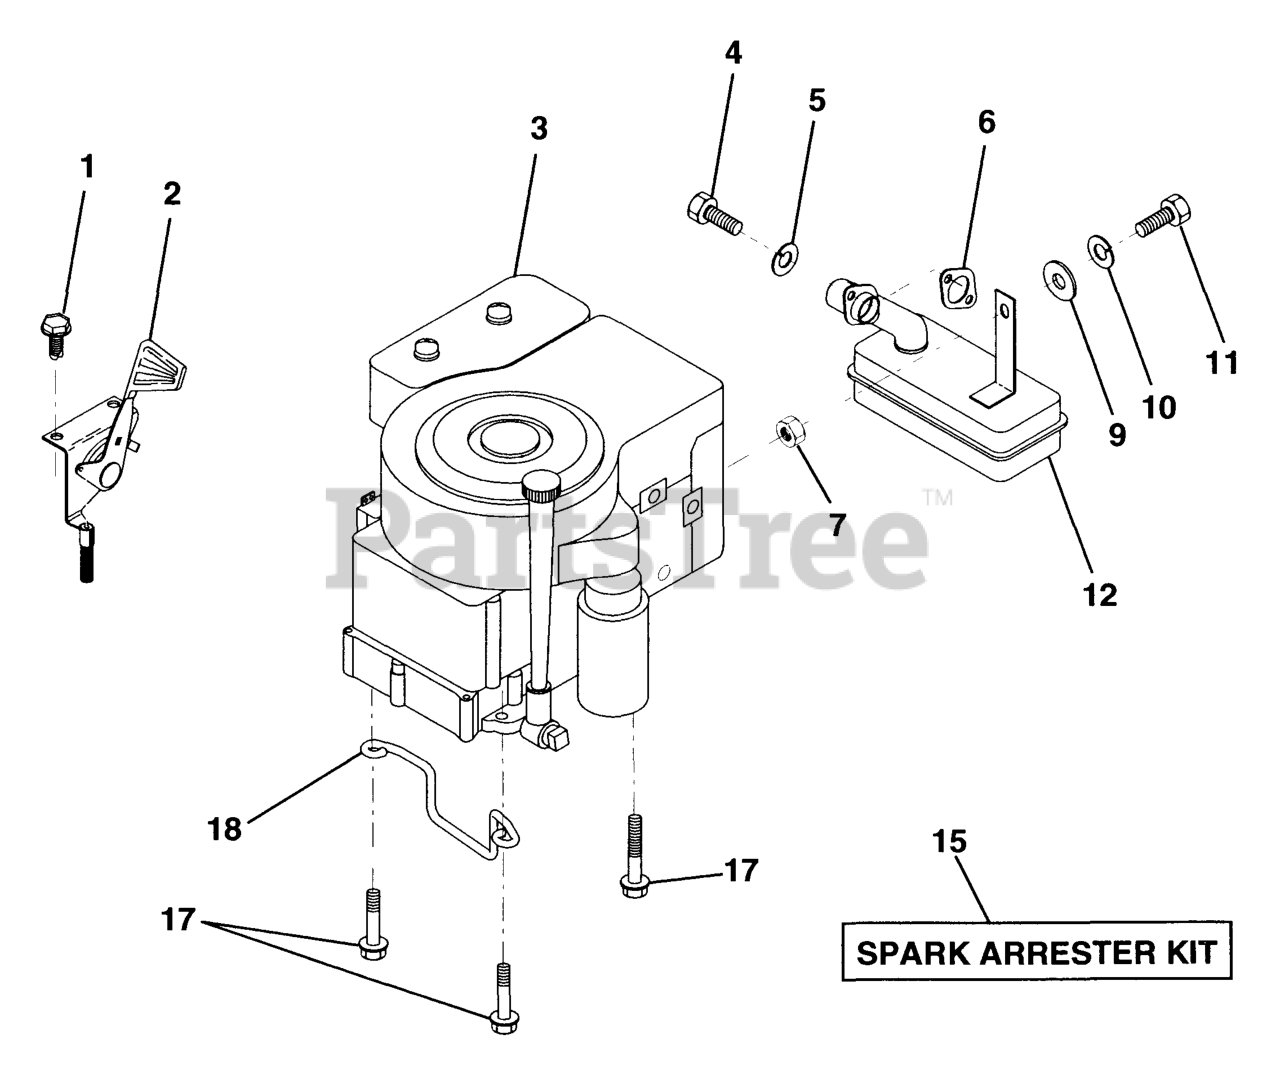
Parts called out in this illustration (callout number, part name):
1	SCREW
2	CONTROL.TH/CH.RH.BLK.FLG.26
3	Engine, Briggs and Stratton
4	SCREW
5	WASHER.LOCK.HVY.HLCL.SPR.5/16
6	GASKET ENGINE
7	NUT
9	WASHER
10	LOCKWASHER
11	BOLT
12	MUFFLER.SINGLE.B&S.12HP
15	KIT.SPARK ARRESTOR 794945 B&S
17	SCREW LT
18	KEEPER,DR BELT GR
